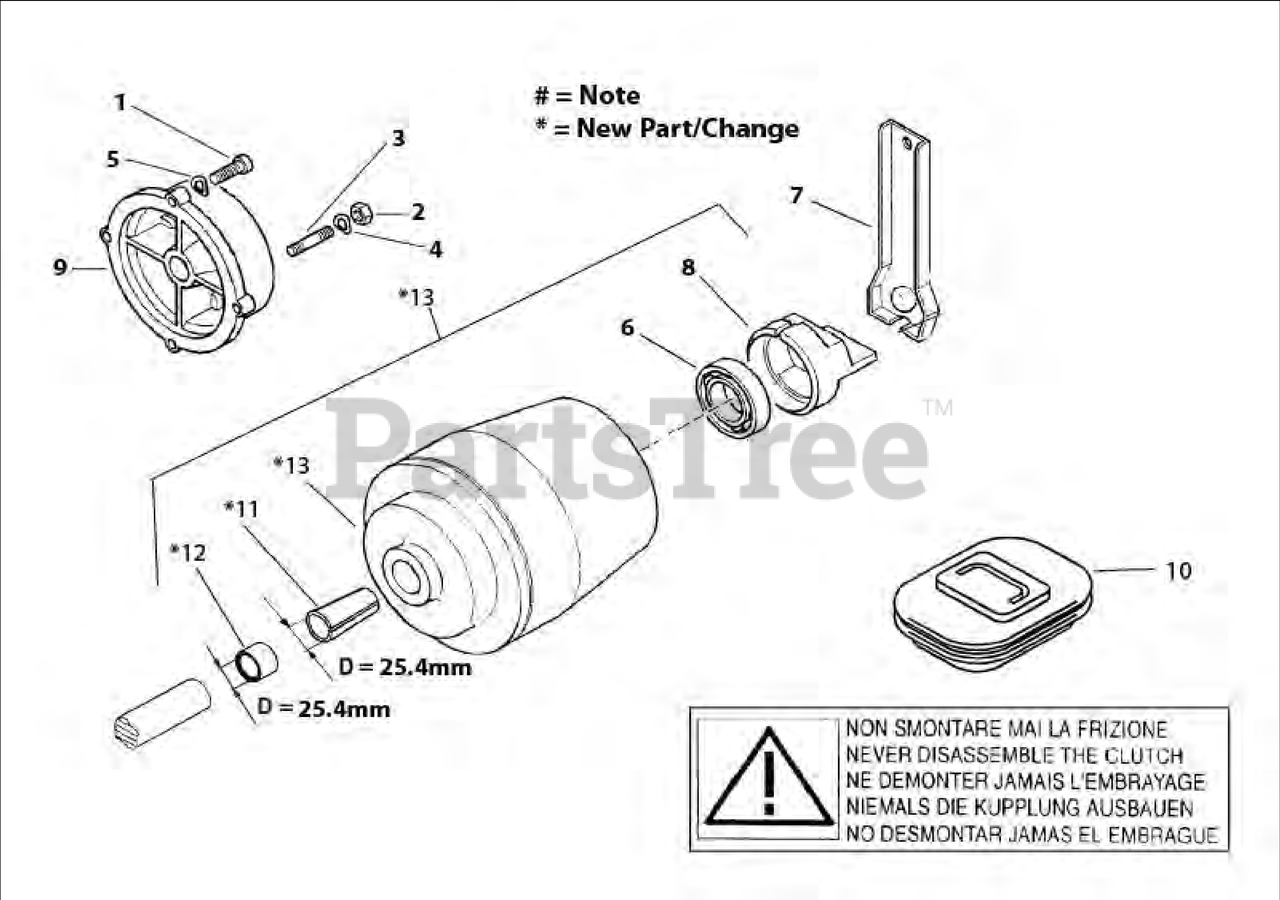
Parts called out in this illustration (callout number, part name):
1	CAPSCREW, 3/8
2	NUT, M8
3	STUD, M8X40X14X4
4	WASHER, LOCK, M8.4
5	WASHER, WAVEY M10.4
6	BEARING 6203 2RS 17X40X12
7	CLUTCH LEVER
8	CONE PUSHER
9	FLANGE, ENGINE
10	BOOT/BELLOWS
11	TAPERED BUSHING D=25.4mm
12	SPACER 18mm D=25.4mm
13	CONE CLUTCH (INCLUDES # 6,8, *11, *12 & *13)
